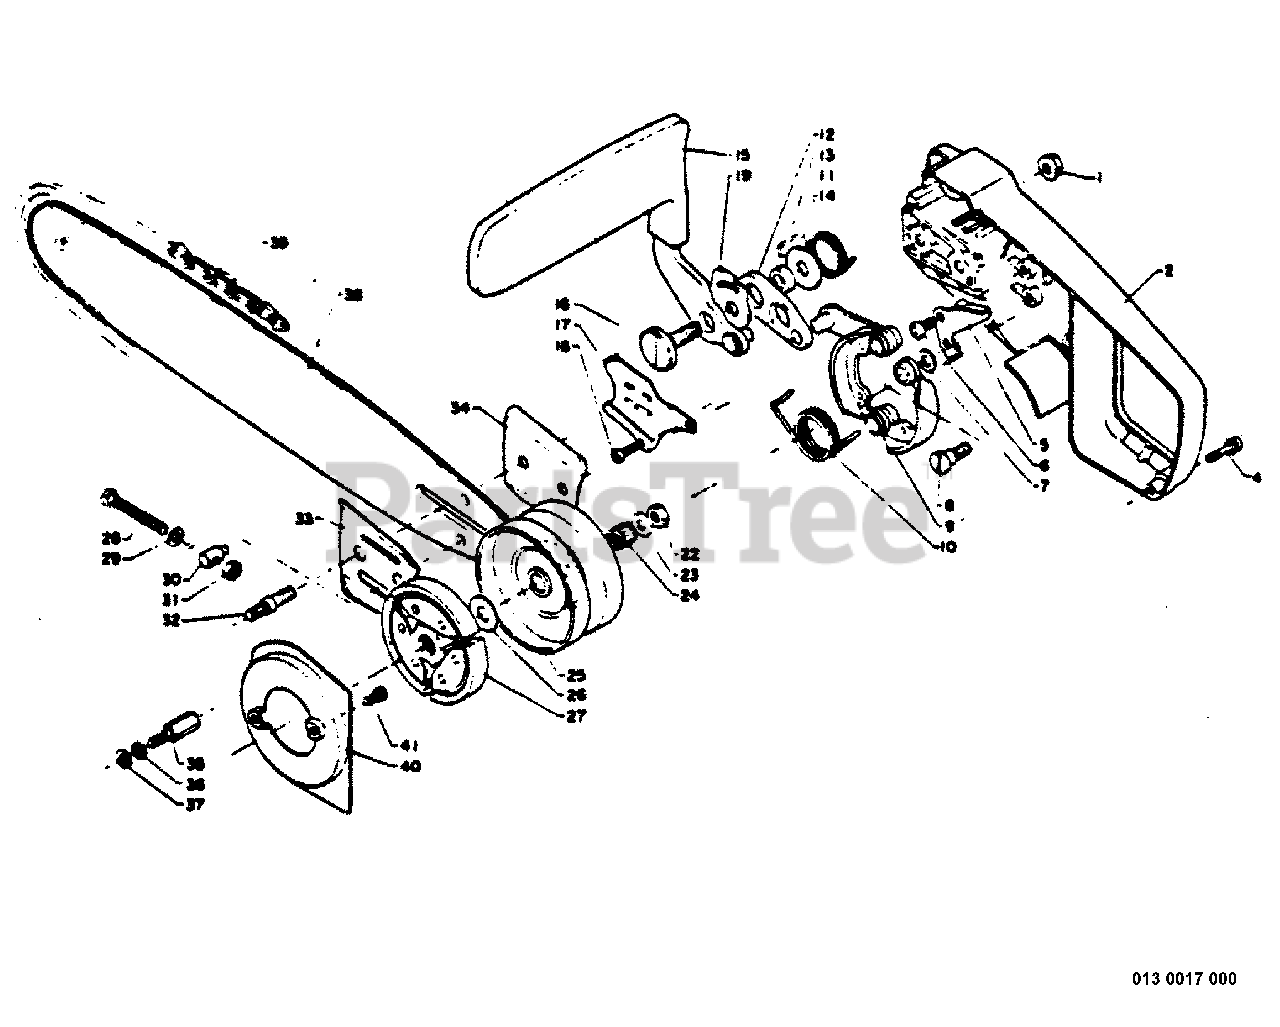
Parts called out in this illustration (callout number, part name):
1	NUT - 6 -- FLANGE
2	COVER, GUIDE BAR
4	SCREW
5	GUIDE, BRAKE SHOE
6	SCREW - 5X8
7	WASHER - 6
9	SHOE, BRAKE
10	SPRING
11	SPACER
12	CONNECTOR
13	SPACER
14	SPRING, RETURN
15	HANDLE, BRAKE
17	SEAL, DUST
18	SCREW - 4X10
19	WASHER
22	LOCKNUT - 6
23	WASHER
24	BEARING, NEEDLE
25	DRUM, CLUTCH
26	WASHER, CLUTCH
27	CLUTCH ASSY
28	SCREW, TENSIONER
29	WASHER - 5
30	TENSIONER, CHAIN
31	LOCKNUT - 5
32	STUD, GUIDE BAR
33	PLATE, GUIDE - INNER
34	PLATE, GUIDE - OUTER
35	CATCHER, CHAIN
36	LOCKWASHER - 5
37	WASHER - 5
38	GUIDE BAR - 14" (35cm)
38	GUIDE BAR - 35" (89cm)
38	GUIDE BAR - 40" (101cm)
39	SAW CHAIN - 25-76E
39	SAW CHAIN - 25 AP-76E
39	SAW CHAIN - 25 AP-84E
40	SEAL, DUST
41	SCREW - 4X8
